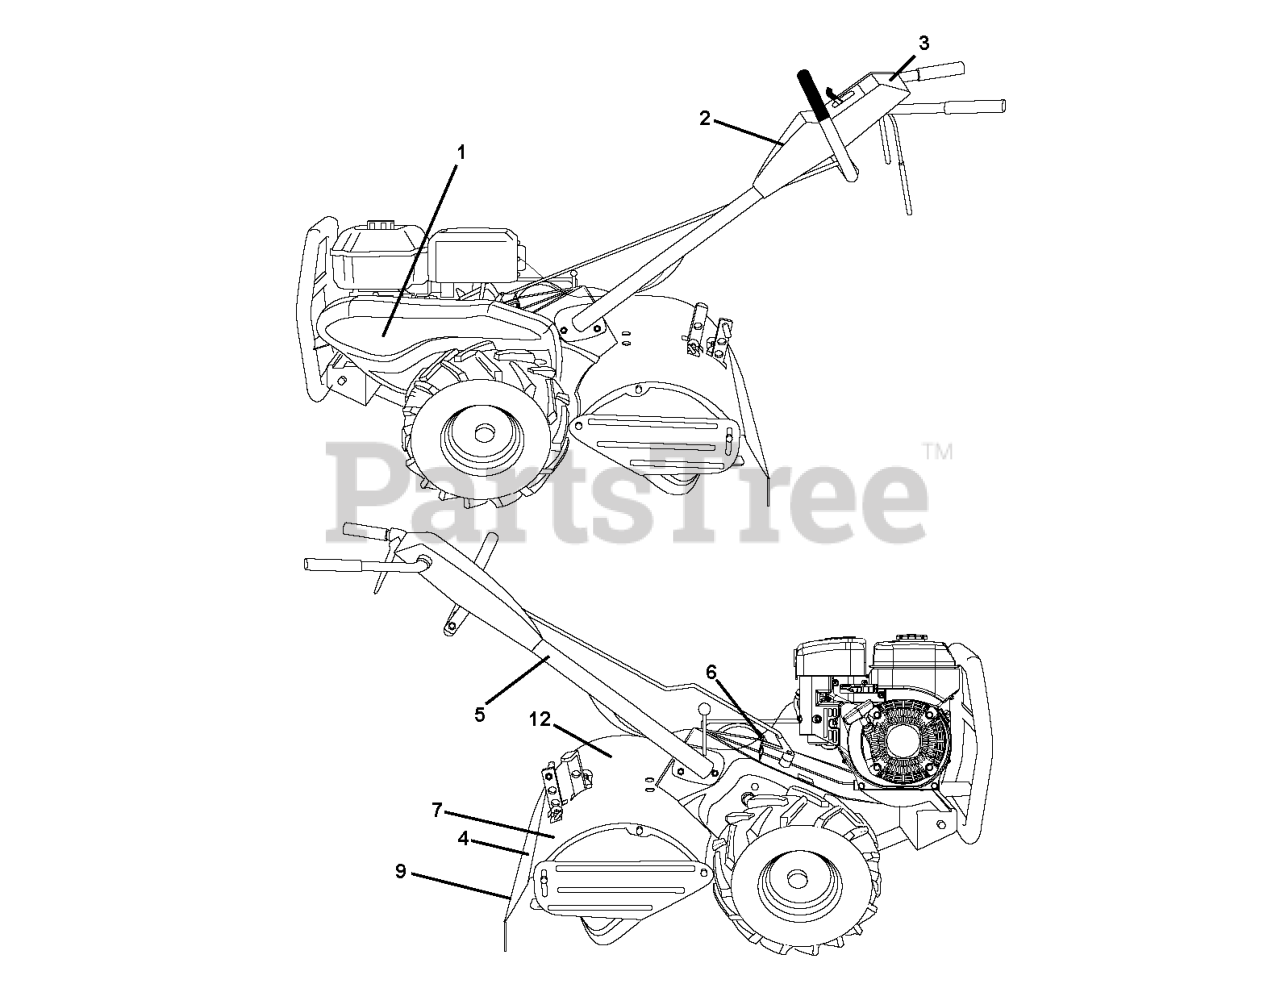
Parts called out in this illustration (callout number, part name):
1	DECAL.HOOD.LOGO.ORANGE.HUSQVAR
3	DECAL.TILLER.CNSL.INS.
4	DECAL.SHIELD.TN.DRT.REAR.SY
5	DECAL.PLACEMENT.HAND.SYMBOLS
6	DECAL.SHIFT.INDICATOR.DRT
9	DECAL.WARNING.4-SYM.TILLER.INT
